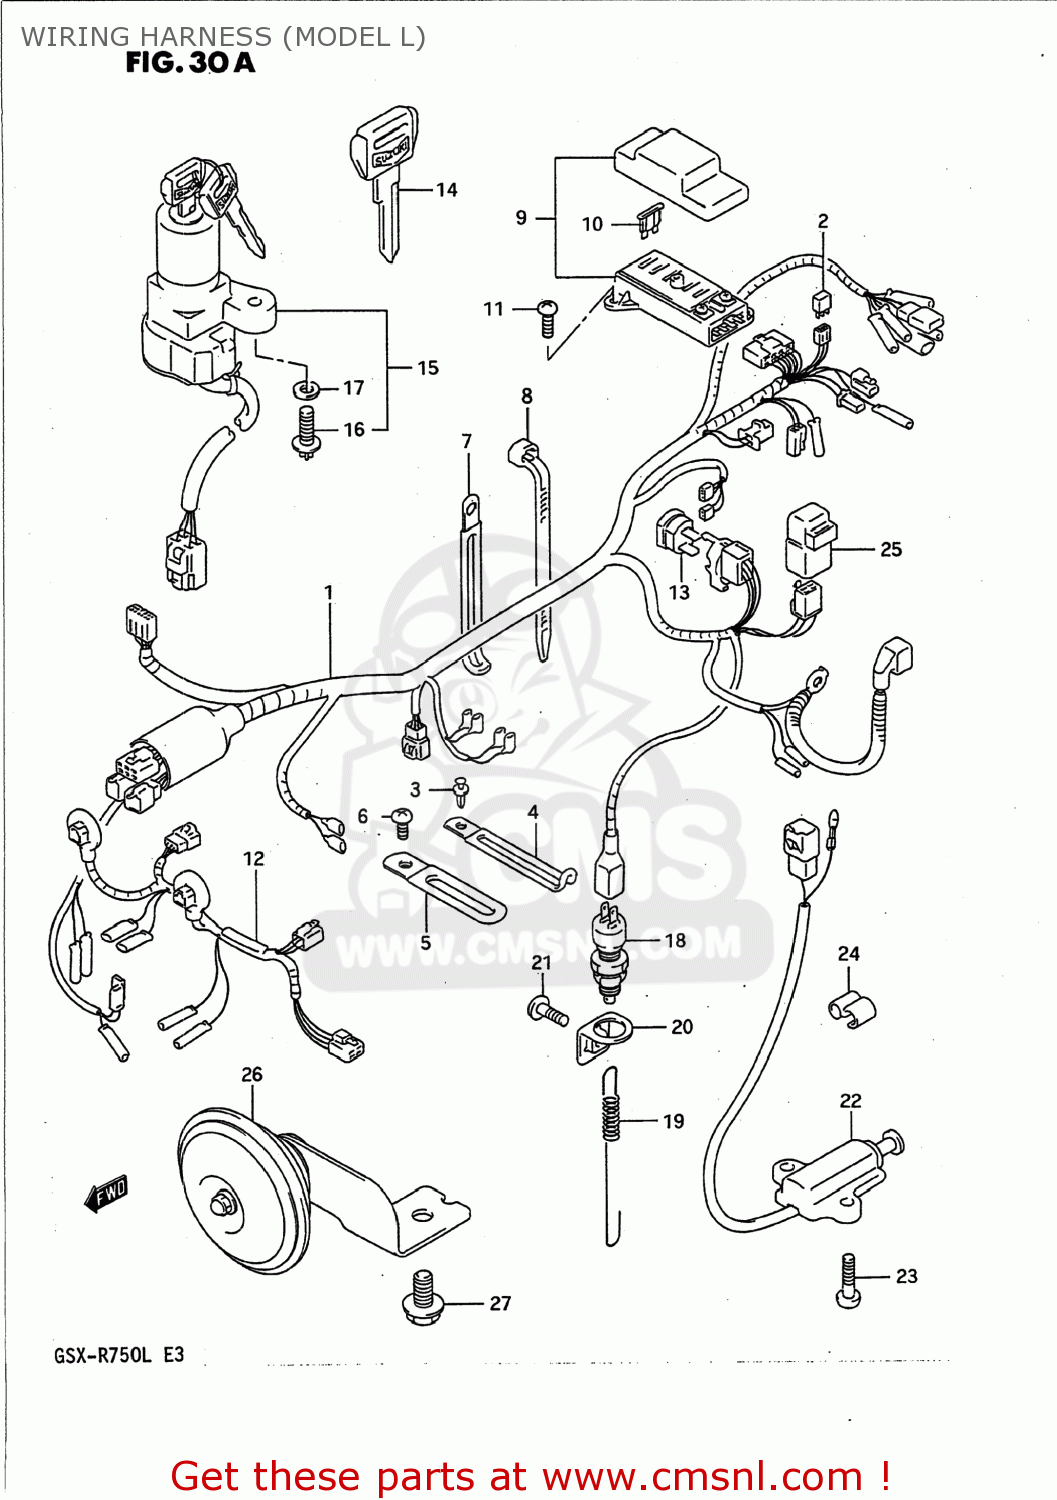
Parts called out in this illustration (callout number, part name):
1	HARNESS,WIRING
2	DIODE(STANLEY DE8804)
3	CLIP
4	CLAMP
5	CLAMP
6	SCREW
7	CLAMP
8	CLAMP(L:125)
9	BOX ASSY,FUSE
10	FUSE(10A)
11	SCREW
12	WIRE,HEADLAMP LEAD
13	BREAKER ASSY,CIRCUT
14	KEY,BLANK
15	LOCK ASSEMBLY,STEERING
16	SCREW(6X18)
17	WASHER
18	SWITCH ASSY,STOP LAMP
19	SPRING
20	BRACKET,STOP LAMP SWITCH
21	SCREW(6X12)
22	SWITCH ASSEMBLY,SIDE STAND
23	SCREW
24	CLIP
25	RELAY ASSEMBLY
26	HORN ASSEMBLY
27	BOLT 8X12
